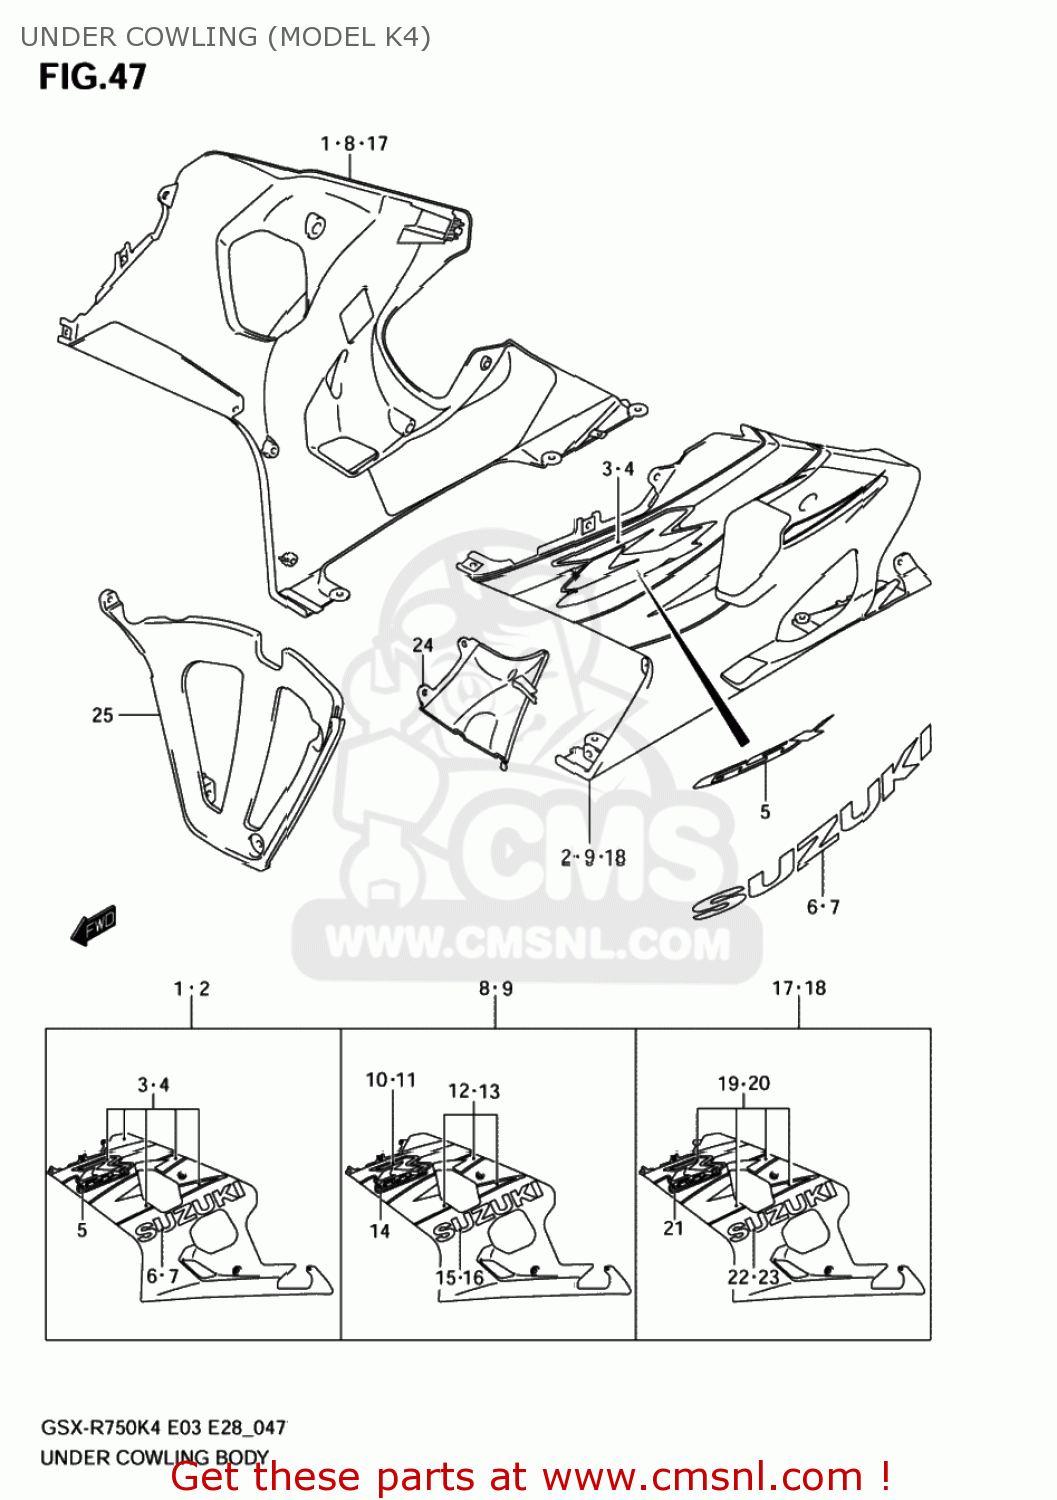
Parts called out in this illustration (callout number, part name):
1	COWLING ASSY,UNDER,R
2	COWLING ASSY,UNDER,L
3	TAPE SET,COWL UNDER,R
4	TAPE SET,COWL UNDER,L
5	EMBLEM,GSX
6	EMBLEM,R
7	EMBLEM,L
8	COWLING ASSY,UNDER,R
9	COWLING ASSY,UNDER,L
10	TAPE,COWL UNDER,R
11	TAPE,COWL UNDER,L
12	TAPE SET,COWL UNDER,R
13	TAPE SET,COWL UNDER,L
14	EMBLEM,GSX
15	EMBLEM,R
16	EMBLEM,L
17	COWLING ASSY,UNDER,R
18	COWLING ASSY,UNDER,L
19	TAPE SET,COWL UNDER,R
20	TAPE SET,COWL UNDER,L
21	EMBLEM,GSX
22	EMBLEM,R
23	EMBLEM,L
24	COWLING,UNDER INNER,L
25	COWLING,UNDER CTR
